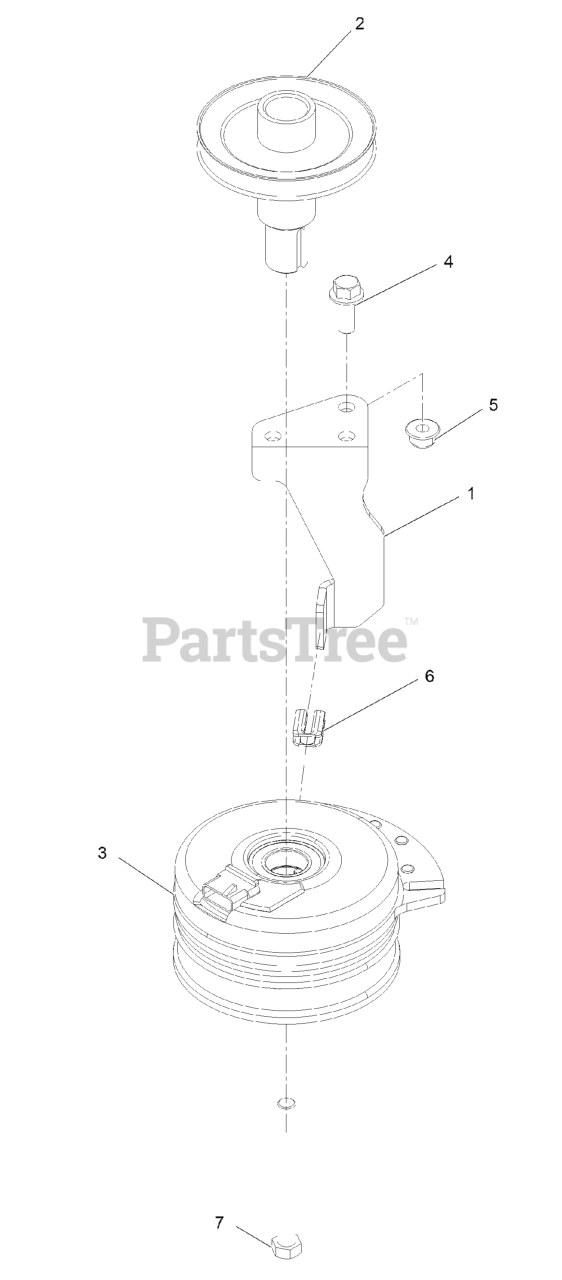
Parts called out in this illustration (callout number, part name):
1	Stop - Clutch (Narrow)
2	Pulley-Engine
3	CLUTCH-ELECTRIC
4	SCREW-HHF 3/8-16 X 1
5	NUT-HF, NI
6	ISOLATOR-CLUTCH
7	SCREW-HH
